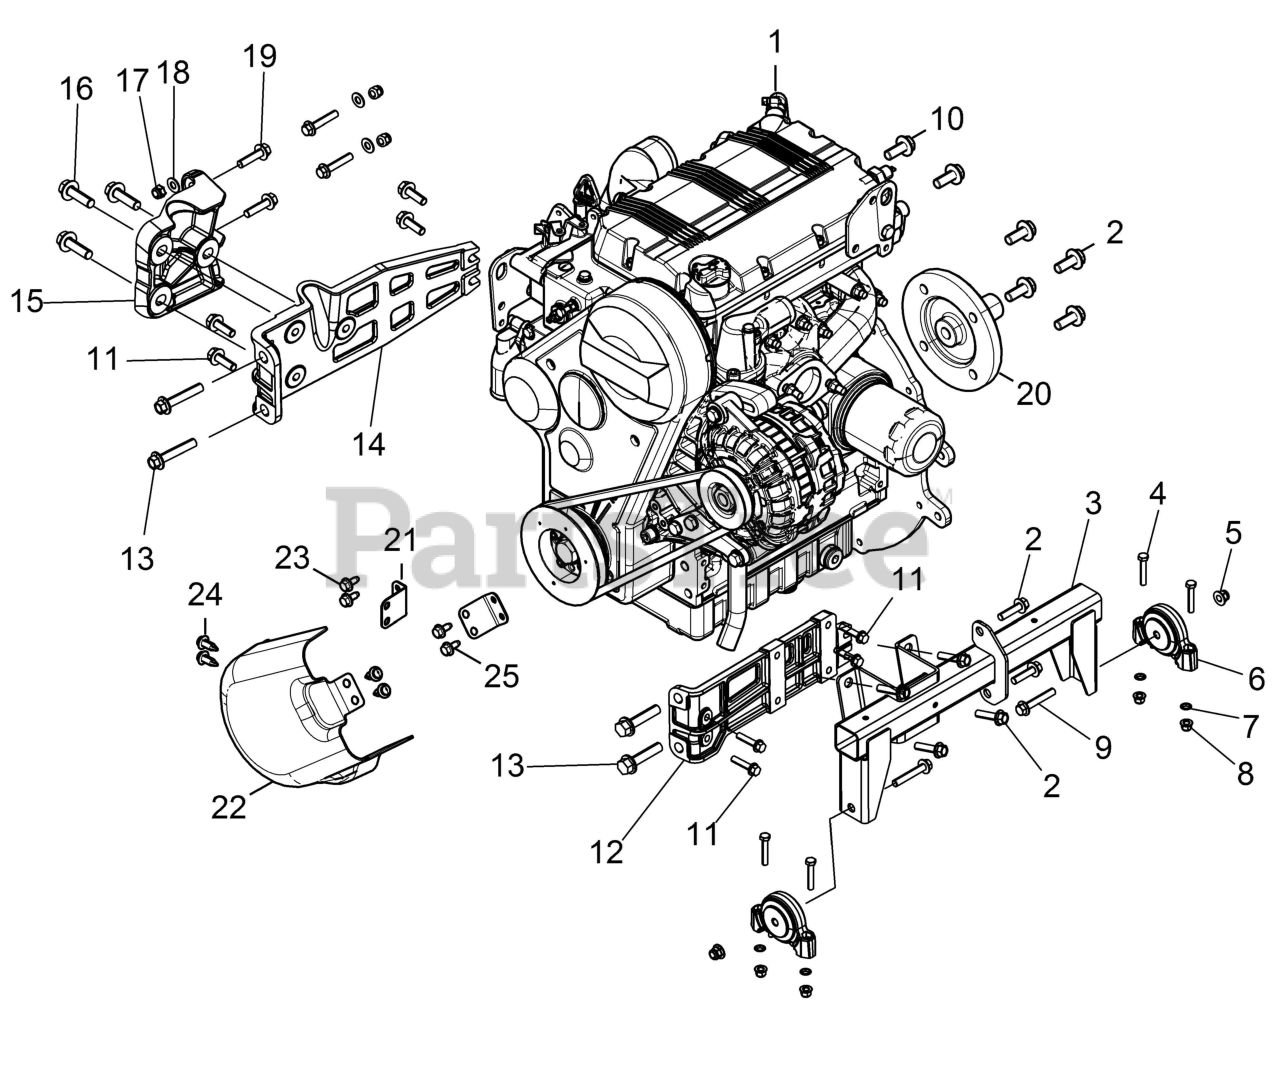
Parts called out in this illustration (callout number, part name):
1	ASM-ENG KDW1003-5143
2	SCR-M10X1.5X25 8.8 HXFL ZOD
3	WELD-MOUNT,ENGINE,BLK
4	SCR-HH M8X1.25X45 8.8 ZOD
5	NUT-M10X1.25,FLG,NYLOC-OLIVE D
6	MOUNT-ISOLATOR,DRIVELINE
8	NUT-M8X1.25,FLG,NYLOC-OLIVE D
9	BOLT-M10X1.25X60,HXFLG-OLIVE D
10	SCR-HXFL-M8X1.25X20 8.8 ZOD P3
11	BOLT-M8X1.25X25,HXFLG-OLIVE D
12	COUPLER-L-ENGINE,FRONT
13	SCR-HXFL-M12X1.75X30 ZOD
14	COUPLER, ENGINE, GEARCASE
15	COUPLER-L-ENGINE,GEARCASE
16	SCR-HXFL-M10X1.5X35 10.9 ZOD D
17	NUT-M10X1.5 HFN NYLOC ZOD
18	WASHER,3/8 FW
19	SCR-HXFL-M10X1.5X50 10.9 ZOD
20	ADAPTER-CLUTCH,DSL
21	BRKT,BELT GUARD,MOUNT,BLK
22	COVER,DEBRIS
23	BOLT,M6X1.0X15,HXFLG,TAP/T-OD
24	RIVET-TUFLOK,.315-.325X.787 (5
